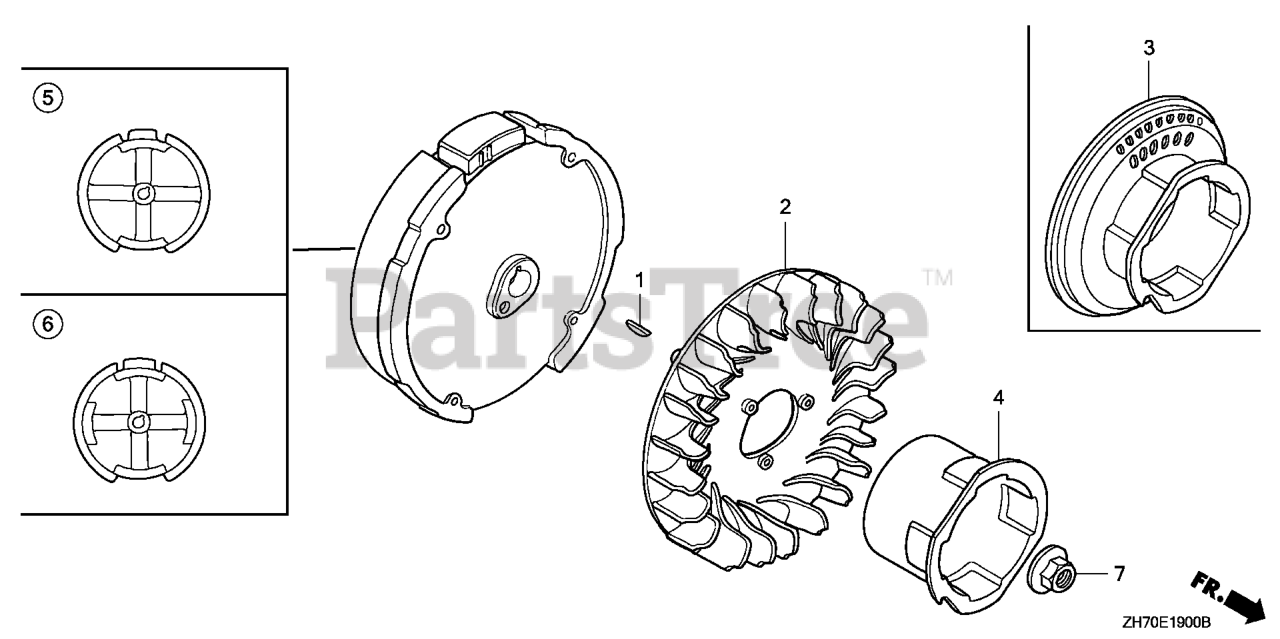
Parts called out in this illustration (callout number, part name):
1	KEY, SPECIAL WOODRUFF (25X18)
2	FAN, COOLING
4	PULLEY, STARTER
5	FLYWHEEL
7	NUT, SPECIAL (14MM)
